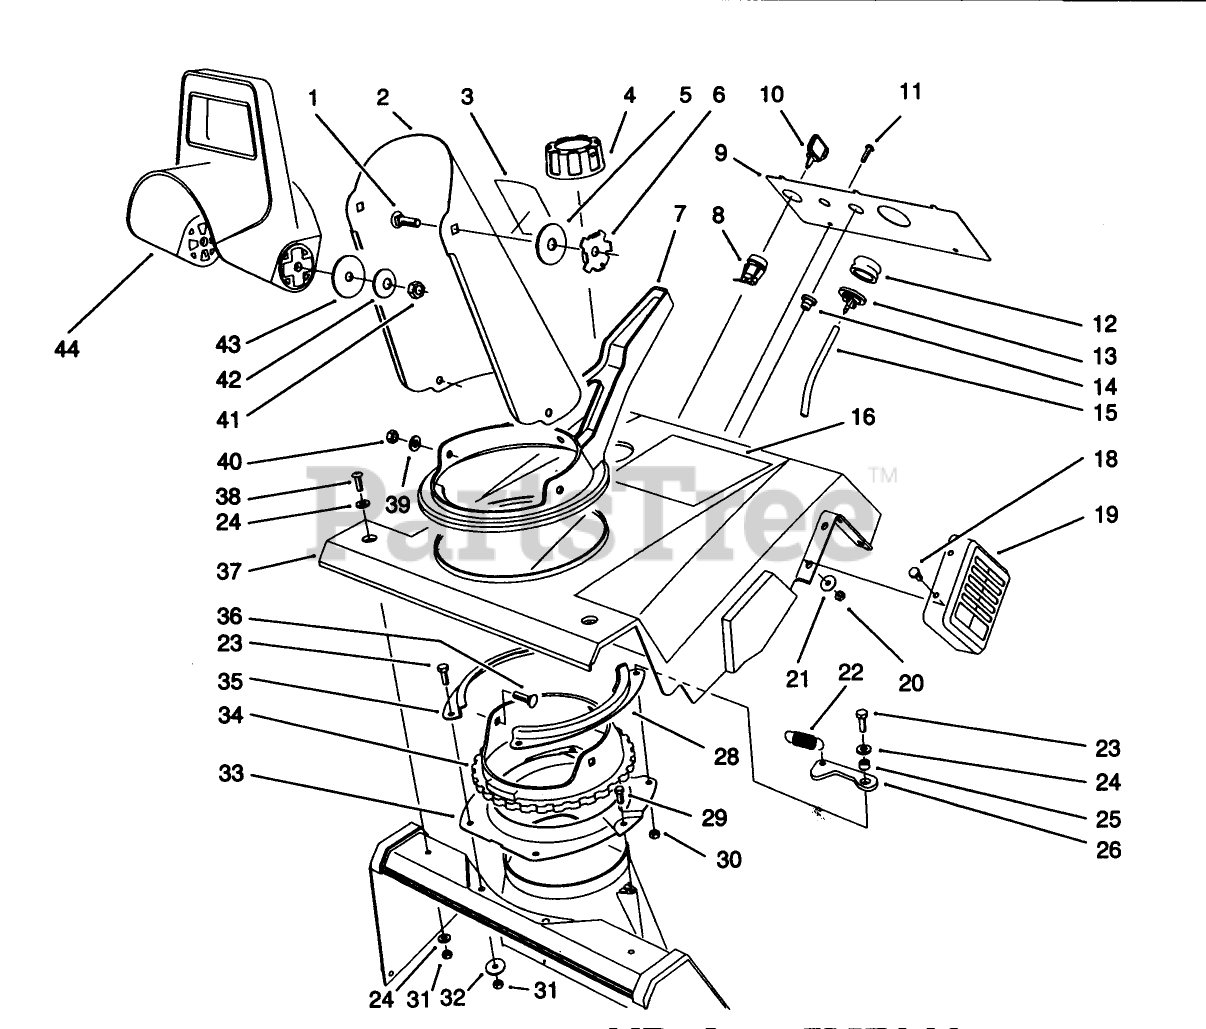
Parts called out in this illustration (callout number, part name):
1	SCREW-CARR
5	WASHER-RUBBER
6	PLATE-FRICTION
7	CHUTE - HANDLE
8	SWITCH
10	KEY-IGNITION
11	SCREW-SHWH, THREAD FORMING
12	BULB-PRIMER
13	BODY-PRIMER
14	GUIDE-ROPE, STARTER
15	HOSE-PRIMER
16	DECAL - CCR1000
18	SCREW-HWH
20	NUT-LOCK, NI
21	WASHER-FLAT
22	SPRING-EXTENSION
23	SCREW-HH
24	WASHER-FLAT
25	SPACER-BLADE, ROTOR
26	DETENT
29	SCREW-PLASTITE
30	NUT-LOCK, NI
31	NUT-LOCK, NI
32	WASHER-FLAT
34	GEAR RING, CHUTE
36	SCREW-CARR
38	SCREW-PPH
39	WASHER-FLAT
40	NUT-KEPS
41	NUT-LOCK, NI
42	WASHER-BELLEVILLE
43	WASHER-FLAT
44	CHUTE-DEFLECTOR
